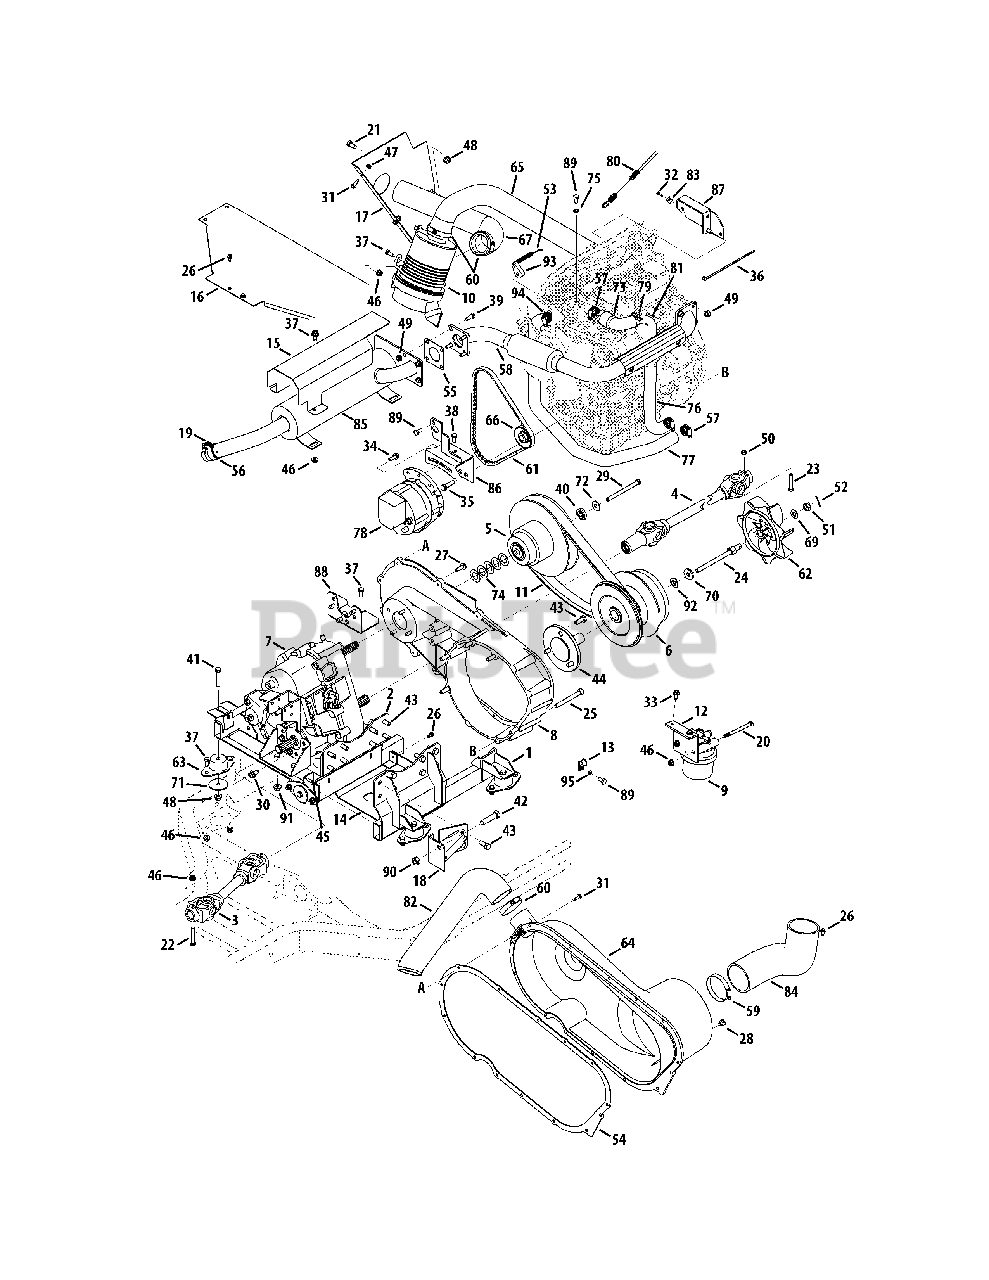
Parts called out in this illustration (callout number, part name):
1	Tray Assembly, Engine, Yanmar
2	Tray Assembly, Engine, Trans
3	Shaft Assembly, Rr/prop
4	Shaft Assembly, Frt/prop, Hilliard
5	Clutch Assembly, Cvt, Driven
6	Clutch Assembly, Driver, Yanmar
7	Case Assembly, Transfer
8	Housing Assembly, Cvt, Machine
9	Filter Assembly, Diesel
10	Filter Assembly, Air Cleaner
11	Belt, Cvt, 4x4
14	Shield, Oil, Engine
15	Exhaust, Shield, Heat
16	Plate, Heat, Shield, Yanmar
18	Bracket Mount, Lower, Alternator
20	Hex Head Screw, 5/16-18, 4.00
21	Hex Head Screw, 3/8-16, .75
22	Hex Head Screw, 5/16-18, 2.00
23	Hex Head Screw, 5/16-18, 1.875
24	Hex Head Screw, 7/16-20, 5.00
25	Screw, M10-1.50
26	Screw, Tt, 1/4-20, 0.500, Hxindwsh
27	Screw, Tt, 5/16-18, 1.000, Hxindwsh
28	Screw, B, 5/16-12, 0.500, Hxindwsh
29	Hex Head Screw, 3/8-24, 3.50
30	Screw, Tt, 3/8-16, 0.750, Hxindwsh
31	Screw, Tt, 1/4-20, 0.750, Hxindwsh
32	Screw, #10-16, 0.625, Hxindwsh
33	Screw, 5/16-18, 0.750, Hxindwsh
34	Hex Head Screw, 5/16-18, .875
35	Hex Head Screw, M8-1.5, 35 mm
36	Tie, Cable
37	Hex Head Screw, 5/16-18, .75
38	Hex Head Screw, 1/4-20, .75
39	Hex Head Screw, 5/16-18, .875
40	Spacer, Shoulder
41	Hex Head Screw, 3/8-16, 2.00
42	Hex Head Screw, 1/2-13, 2.00
43	Hex Head Screw, M10-1.5, 25mm
44	Shaft, Output, Yanmar, Tapered
46	Nut, Flange Lock, 5/16-18, Nylon
47	Nut, Flange Lock, 1/4-20, Nylon
48	Nut, Flange Lock, 3/8-16, Nylon
49	Nut, Flange Lock, 5/16-18, Sd Lk
50	Nut, Hex Lock, 5/16-18, Ctrlk
51	Nut, Hex, 1/2-20, Gr5, Slot
52	Pin, Cot, 3/32, 1.0
53	Spring, Extension
54	Gasket, CVT Cover
55	Gasket, Engine
56	Spark Arrester Screen
57	Clamp, Hose, Adj
58	Pipe, Exhaust, Yanmar
59	Clamp, Hose, Adj
60	Clamp, Hose, Adj 2-3"
62	Impeller, Blo
63	Compression Mount, Eng, Head
64	Cover, Cvt
65	Hose, Air Inlet, Yanmar
67	Hose, Air Inlet
68	Washer, Flat, .330 x .630 x .0635
69	Washer, Flat, .510 x 1.00 x .060
70	Washer, Flat, .450 x 1.250 x .164
71	Washer, Flat, .38 x 2.00 x .12
72	Washer, Bell, .396 x 1.140 x .095
73	Tube, Upr, rr, Rdtr, Yanmar
74	Washer, Flat, .793 x 1.368 x .025
75	Washer, Lock, 5/16 Ext Tooth
76	Tube, lwr, rdtr
77	Hose, Rdtr, Rr, Yanmar
78	Alternator, Aux, 65 Amp
79	Fitting, Petcock, 1/8"
80	Cable, Throttle Control, Yanmar
81	Tube, Rdtr
82	Hose, CVT, Exhaust
83	Clamp, Casing
84	Tube, Cvt, Intake
86	Assembly Mount, Alternator
87	Bracket, Throttle Mount
88	Bracket, Transmission Mount, rr
89	Hex Head Screw, M8-1.25
90	Nut, Hex Lock, 1/2-13
91	Nut, M8-1.25
92	Spacer, Shoulder
93	Bracket, Throttle, Spring, Return
94	Clamp, Hose, Adj
95	Washer, Flat 1/4"
